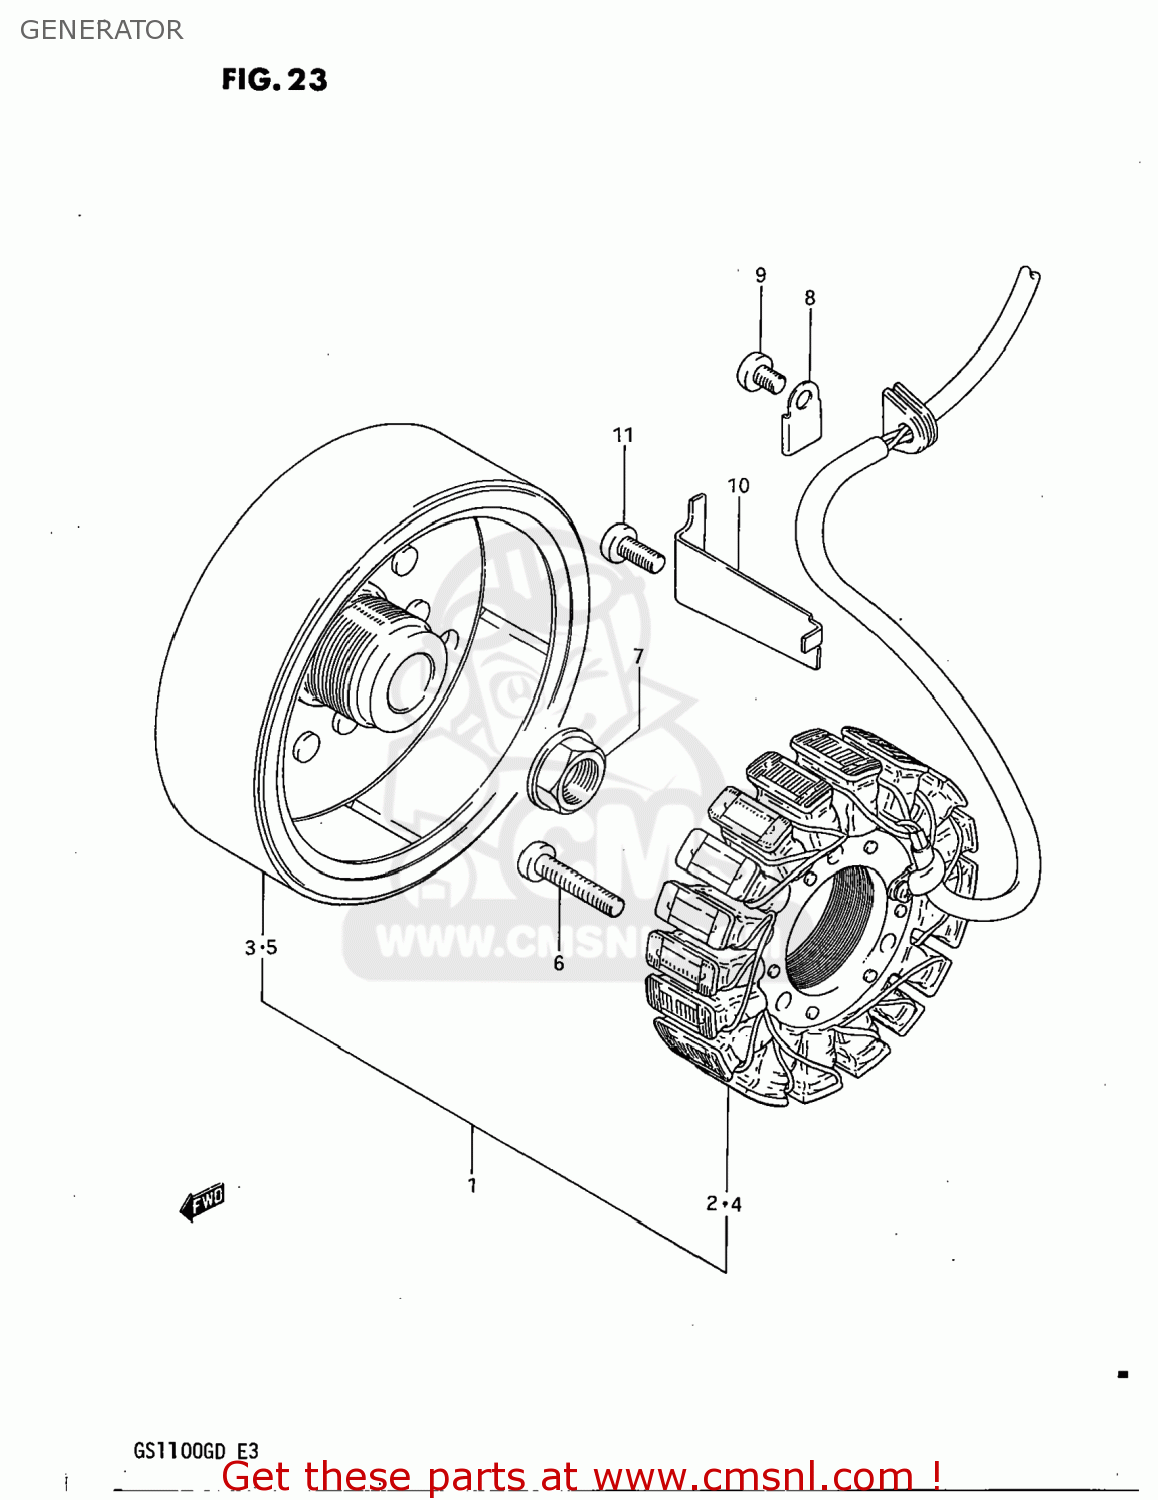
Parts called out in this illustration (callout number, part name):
1	GENERATOR ASSEMBLY
2	STATOR ASSEMBLY
3	ROTOR ASSEMBLY
4	STATOR ASSEMBLY
5	ROTOR ASSEMBLY
6	SCREW 6X30
7	NUT,GENERATOR ROTOR
8	CLAMP,GENERATOR LEAD WIRE
9	SCREW
10	CLAMP,GENERATOR LEAD WIRE
11	SCREW
